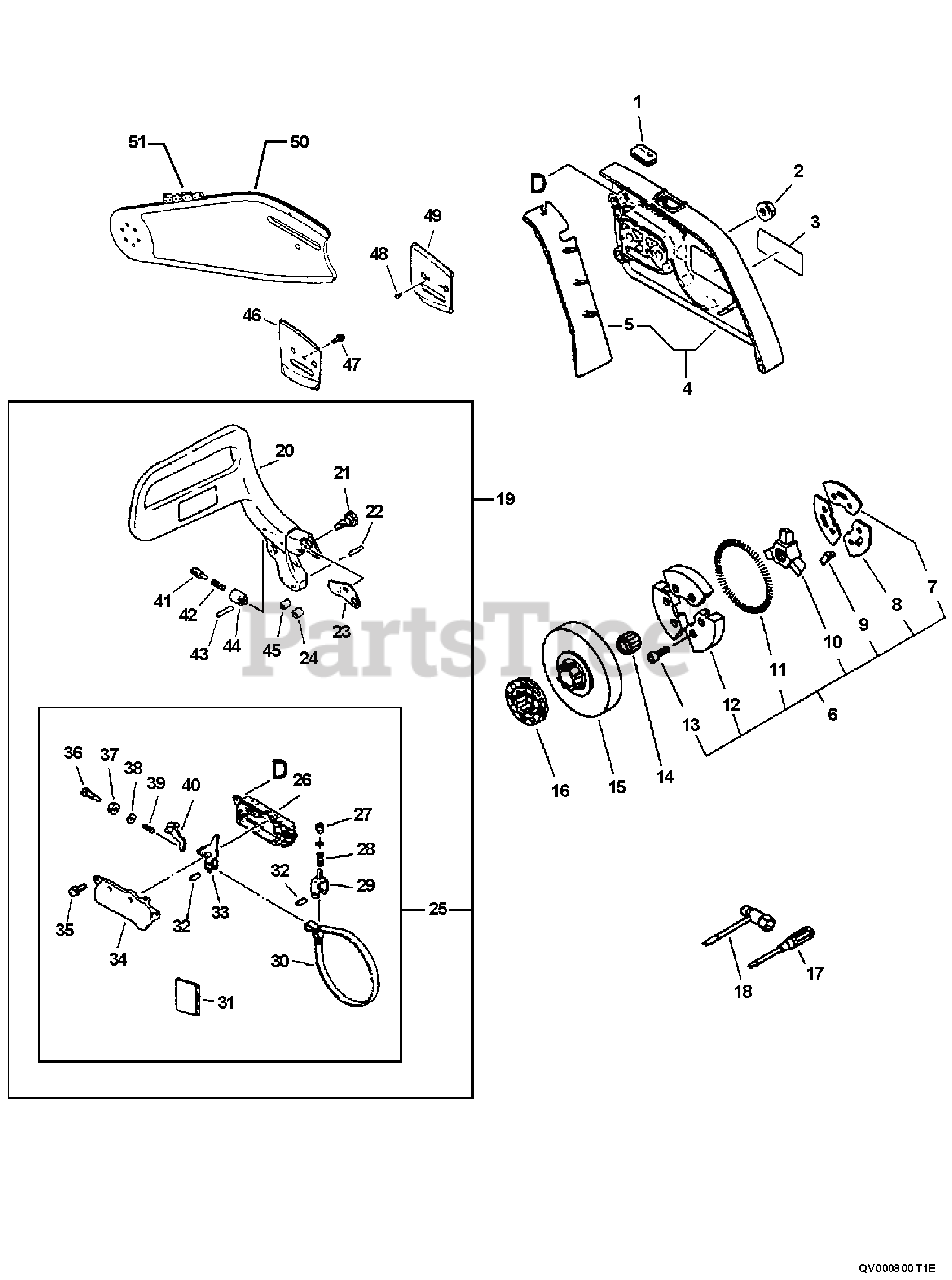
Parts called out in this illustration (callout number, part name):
2	NUT - FLANGE
3	LABEL - ECHO
4	GUARD, SPROCKET
6	CLUTCH ASSY
7	PLATE, CLUTCH
8	PLATE, CLUTCH
9	PLATE, SPRING
10	HUB, CLUTCH
11	SPRING, CLUTCH
12	CLUTCH SHOE SET
13	SCREW - 4X8
14	BEARING, NEEDLE
15	DRUM, CLUTCH
16	SPROCKET, RIM
17	SCREWDRIVER
18	T-WRENCH - 13X19mm
19	CHAIN BRAKE ASSY
20	LEVER, BRAKE
25	CHAIN BRAKE ASSY
26	COVER, BRAKE
29	ADJUSTER, BRAKE BAND
30	BAND, BRAKE
32	PIN - SPRING
33	LEVER, BRAKE
34	COVER, BRAKE
35	SCREW - 4X10
39	SPRING, BRAKE
40	STOPPER, BRAKE
45	SPACER
46	PLATE, GUIDE - INNER
47	SCREW - 4X8
48	SCREW - 3X6
49	PLATE, GUIDE - OUTER
50	GUIDE BAR - QUICKVENT
51	CHAIN -- CARBICHAIN QUICKVENT
